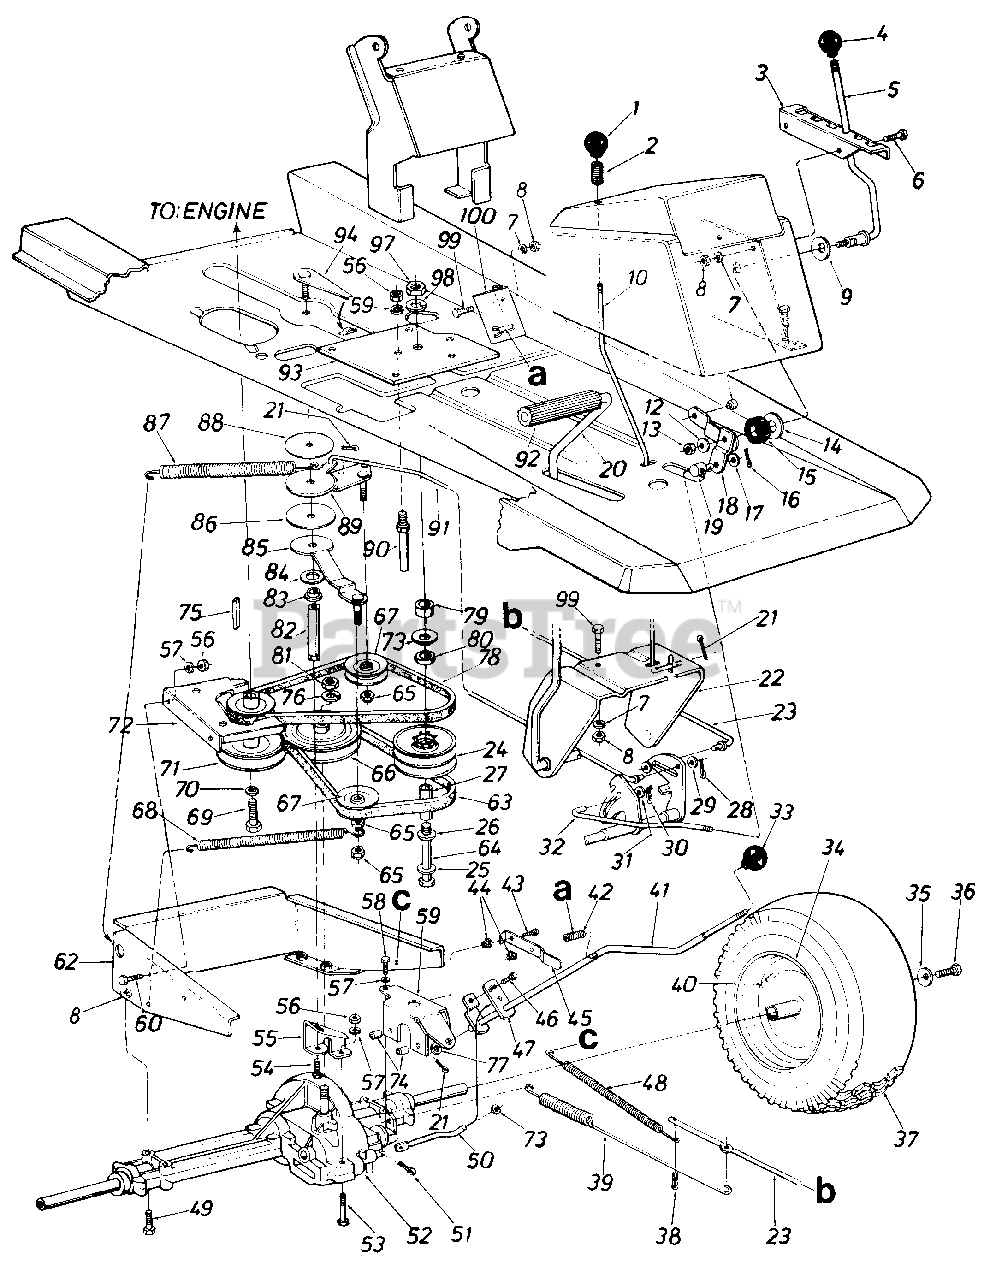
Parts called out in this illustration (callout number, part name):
1	Ball Knob 1/4-20 Thd. 1.25"
2	Compression Spring
5	Speed Control Lever
6	Truss Mach. Scr. 5/16-18 x .75" Lg.
7	L-Wash. 5/16" I.D.
8	Hex Nut 5/16-18 Thd.
9	Bell-Wash. 345" I.D. x .88"
10	Brake Locking Rod
12	Bell-Wash. .345" I.D. x .08"
13	Hex Cent. L-Nut 5/16-18 Thd.
14	Fl-Wash. .50" I.D. x 1.5" O.D.
15	Rubber Washer
16	Intern. Cotter Pin 1/2" Dia.
17	Fl-Wash. .34" I.D. x .68" O.D.
18	Speed Control Lever Brkt. Ass'y.
19	Ferrule-Engagement
20	ClutchlBrake Pedal Ass'y.
21	Cotter Pin 3/32" Dia. x .75"
22	ClutchlBrake Pedal Ass'y.
24	Variable Speed Pulley Ass'y.
25	Washer .635" I.D. x 3.50" O.D.
26	Thrust Brg. 1.25" O.D. x .56" I.D.
27	Spacer Sleeve 2.71"
28	Cotter Pin 118" Dia. x 1.25"
29	Fl-Wash. .34" I.D. x .60" O.D.
30	Intern. Cot-Pin 5/16" Dia.
31	Fl-Wash. .34" I.D. x.60" O.D.
32	Speed Control Rod
33	Ball Knob
35	Bell-Wash. .345" I.D. x .88"
36	Hex L-Bolt 5/16-24 x .75" Lg.
38	Cotter Pin 1/8" Dia. x 1.25
39	Extension Spring 17.0" Lg.
40	Air Valve
43	C Sink AB S-Tap Scr. #8 x .50" Lg.
44	Push-in Nut #10
45	Spring Switch
46	Hex Bolt 1/4-20 x .50" Lg.
47	Shift Lever Adjusting Link
48	Ext. Spring 81/4" Lg.
49	3/16-18 x 2.50 Hex Bolt
51	Intern. Cotter Pin
52	Transaxle
53	Hex Bolt 1/4-20 x 1.75" Lg.
54	Hex Bolt 3/8-24 x .75" Lg.
55	Torque Rod Bracket
56	Hex Nut 1/4-20 Thd.
57	L-Wash. 1/4" l.D.
58	Self-Tap Mach. Scr. Type "C" 1/4-20 x 1.37" Lg.
59	Shift Lever Support Brkt.
60	Hex Bolt 1/4-20 x 1.00" Lg.
62	Transaxle Support Ass'y.
63	V-Belt
64	Hex Bolt 3/8-16 x 4.5" Lg.
65	Hex Ins. L-Nut 3/8-24 Thd.
66	5/8 V-Pulley 500" I.D. x 6n
67	V-Belt Idler .38" I.D. x 3.06
68	Ext. Spring .50" O.D. x 6.37
69	Hex Bolt 7/16-20 x 1.00" Lg.
70	L-Wash. 7/16" l.D.
71	Engine Pulley .500" O.D. & 3.56" O.D.
72	Upper Eng. Belt Guard
73	Bell-Wash. .4" I.D. x 1.12 0 O.D.
74	Spacer .256" I.D. x .50" O.D.
75	Sq.-Key 1/4" x 2,00n Lg.
76	L-Wash. 1/2" I.D.
77	Fl-Wash. .469 I.D. x .88" O.D.
78	V-Belt
79	Spacer 1.00" x 380" O.D.
80	Washer .56 I.D. x 1.25" O.D.
81	Hex Nut 1/2-13 Thd.
83	Flange Bearing .378
84	Fl-Wash .640" l.D. x 1.24"
85	Idler Bracket Ass'y.
86	Thrust Wash. .635" I.D.
87	Extension Spring 758" Lg.
88	Thrust Wash. 385" I.D.
89	Idler Bracket Ass'y. For Clutch
90	Belt Guard Pin 1/4" Dia.
92	Foot Pad
93	Mtg. Brkt. Variable Pulley
98	L-Wash. 3/8 Heavy Duty
99	Hex Bolt 5/16-18 x .75" Lg.
100	Shift Lever Spring Brkt.
